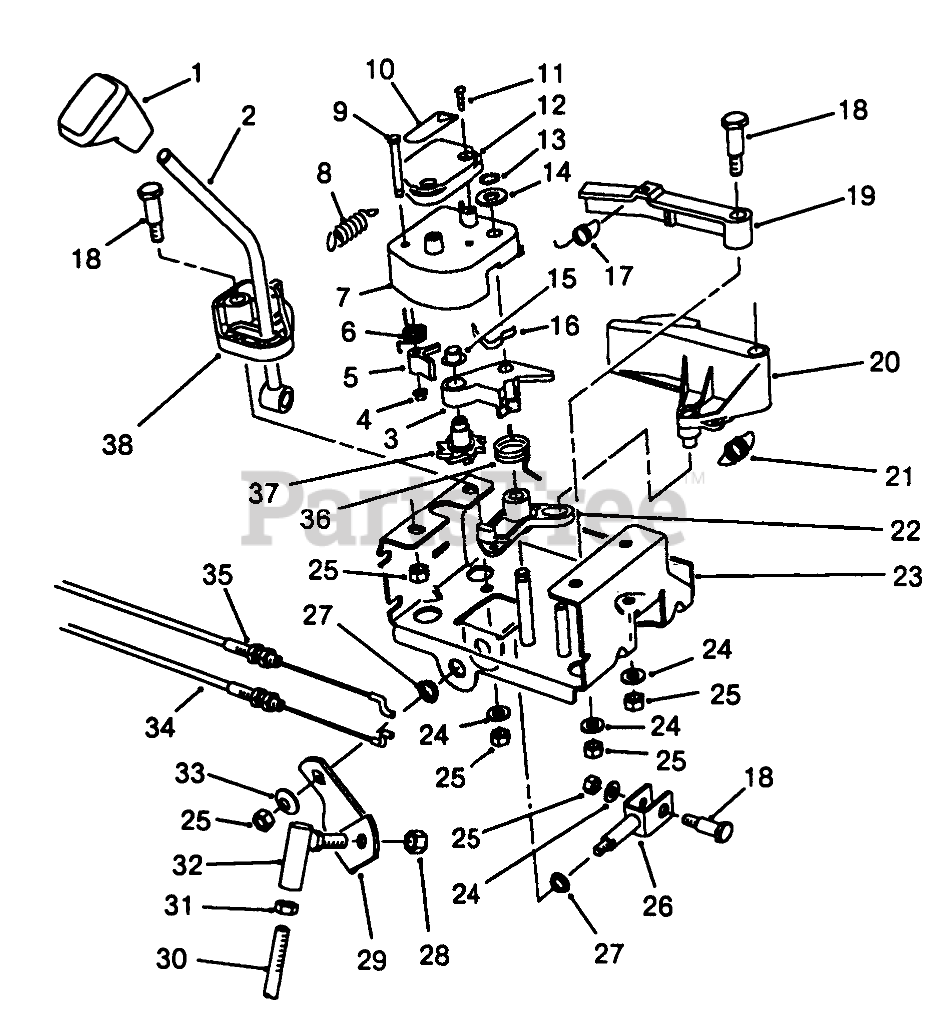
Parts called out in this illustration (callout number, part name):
1	KNOB-SHIFT
2	SHIFT ROD WA
3	LEVER-WHEEL, INDEX
4	NUT-PUSH
5	TANG-INDEX
6	SPRING-TORSION
7	LATCH-LEVER
8	SPRING-EXTENSION
9	PIN-TANG
10	DECAL
11	SCREW-PPH
12	COVER-LATCH
13	RING-RETAINING
14	WASHER-THRUST
15	RETAINER-PUSH ON
16	SPRING-FLAT
17	SPRING-EXTENSION
18	SCREW-SHOULDER
19	LEVER-LOCKOUT
20	LEVER-REVERSE
21	SPRING-EXTENSION
22	LEVER-REVERSE, SWITCH
23	Frame-Control
24	WASHER-PLAIN
25	NUT-LOCK, NI
26	CLEVIS WA
27	BUSHING
28	NUT-LOCK
29	LOWER SHIFT ROD
30	ROD-BENT SHIFT, LOWER
31	NUT-HJ
32	JOINT-BALL
33	WASHER-BELLEVILLE
34	CABLE-GEARBOX
35	CABLE-ARM, LATCH
36	SPRING-TORSION
37	WHEEL-INDEX
38	BASE-LOCKOUT
